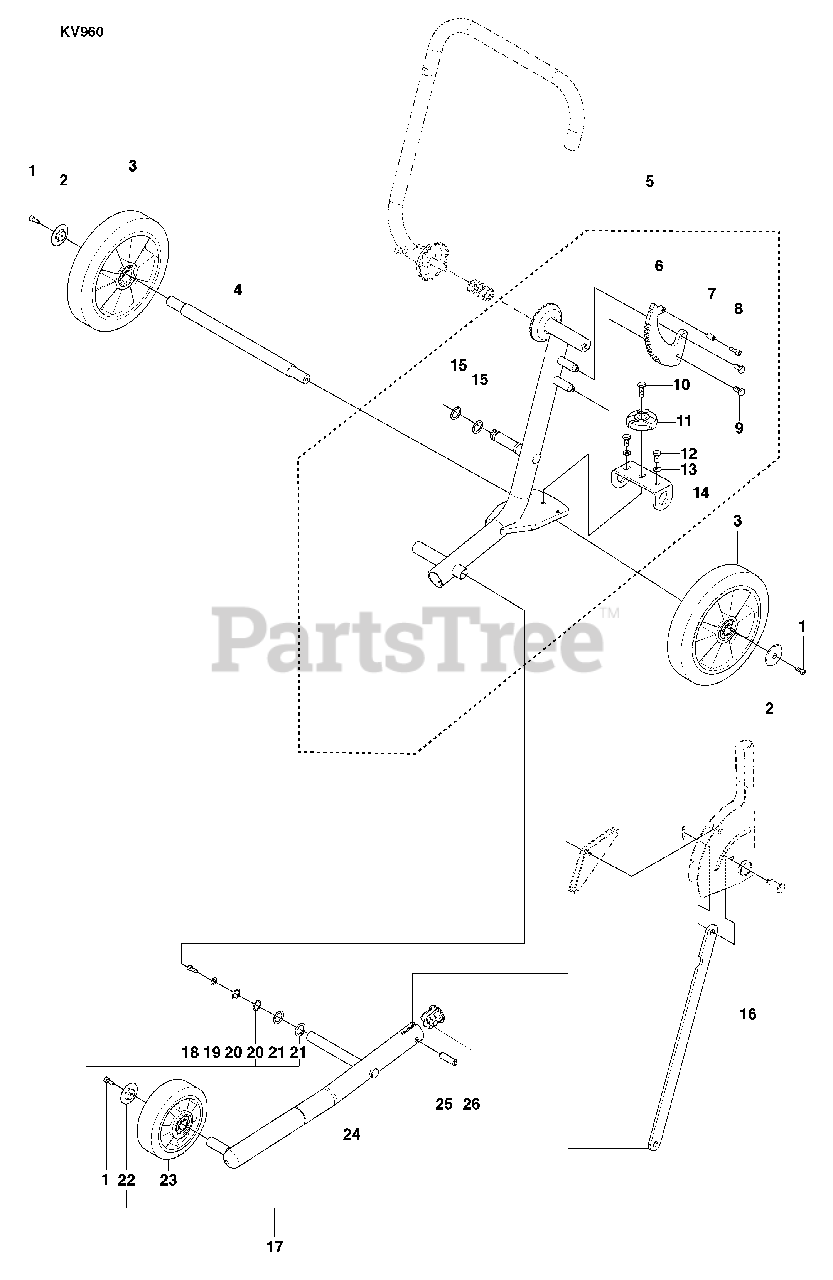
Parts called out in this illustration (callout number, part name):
5	FRAME
7	SPACING SLEEVE
8	SCREW
9	SCREW
17	FRAME TUBE
18	SCREW
21	CUP SPRING
24	FRAME TUBE
25	SPRING PIN
